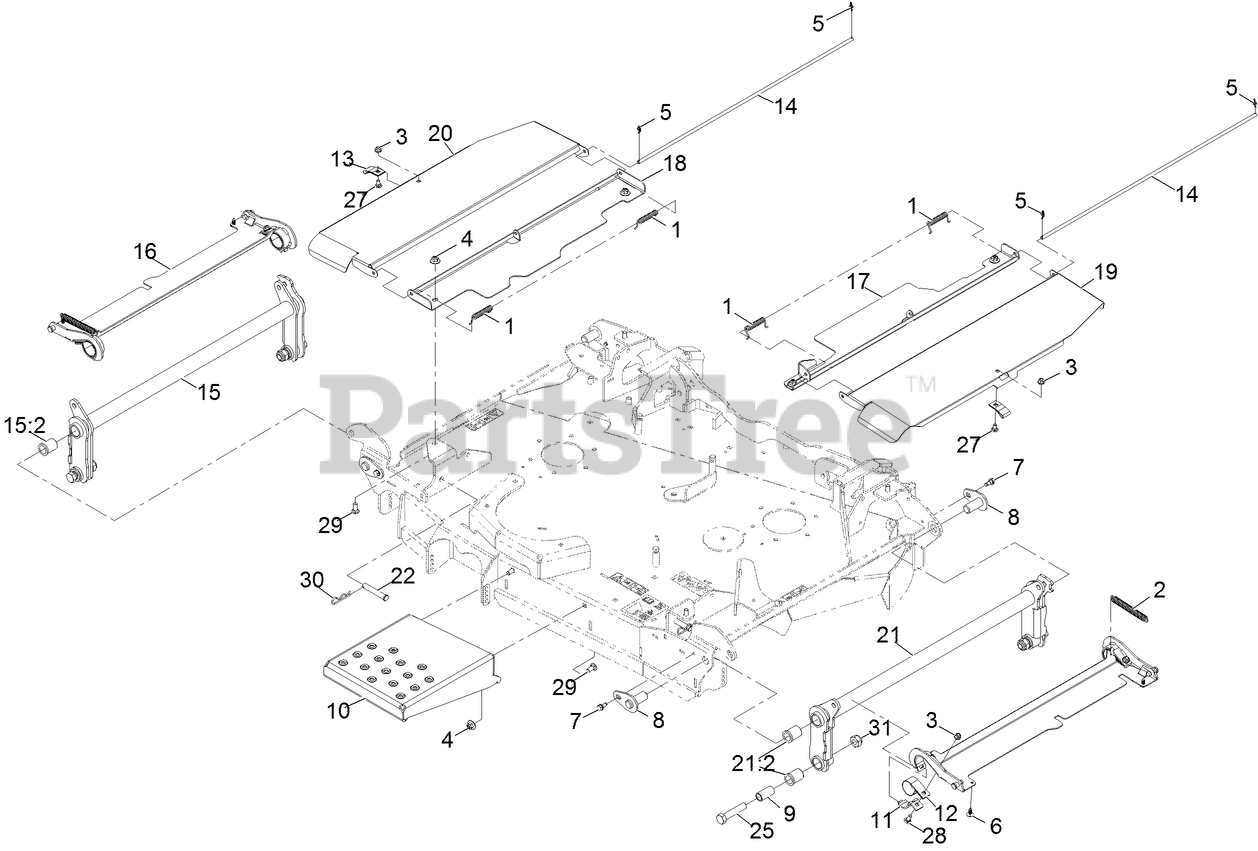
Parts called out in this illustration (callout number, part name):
1	SPRING-TORSION
2	SPRING
3	NUT-HF, NI
4	NUT-FLANGE, NI
5	PIN-COTTER, LOCKING
6	PLUG-PLASTIC
7	SCREW-SHOULDER
8	PIN-DECK
9	BUSHING-FLOAT, DECK
10	PANEL-STEP
11	PLATE-RETAINER, BEARING
12	BEARING-STRAP, NYLON
13	BEARING-STRAP, NYLON
14	COVER-ROD, PIVOT
15	RH FOLD ARM ASM
15:2	BUSHING-FLANGED
16	COVER-WING
17	SHIELD-CENTER, LH
18	SHIELD-CENTER, RH
19	PANEL-SHIELD HINGE, LH
20	PANEL-SHIELD HINGE, RH
21	LH FOLD ARM ASM
21:2	BUSHING-FLANGED
22	PIN-CLEVIS
25	SCREW-HH
27	SCREW-CARR
28	SCREW-CARR
29	BOLT-CARR
30	PIN-HAIR
31	NUT-LOCK
